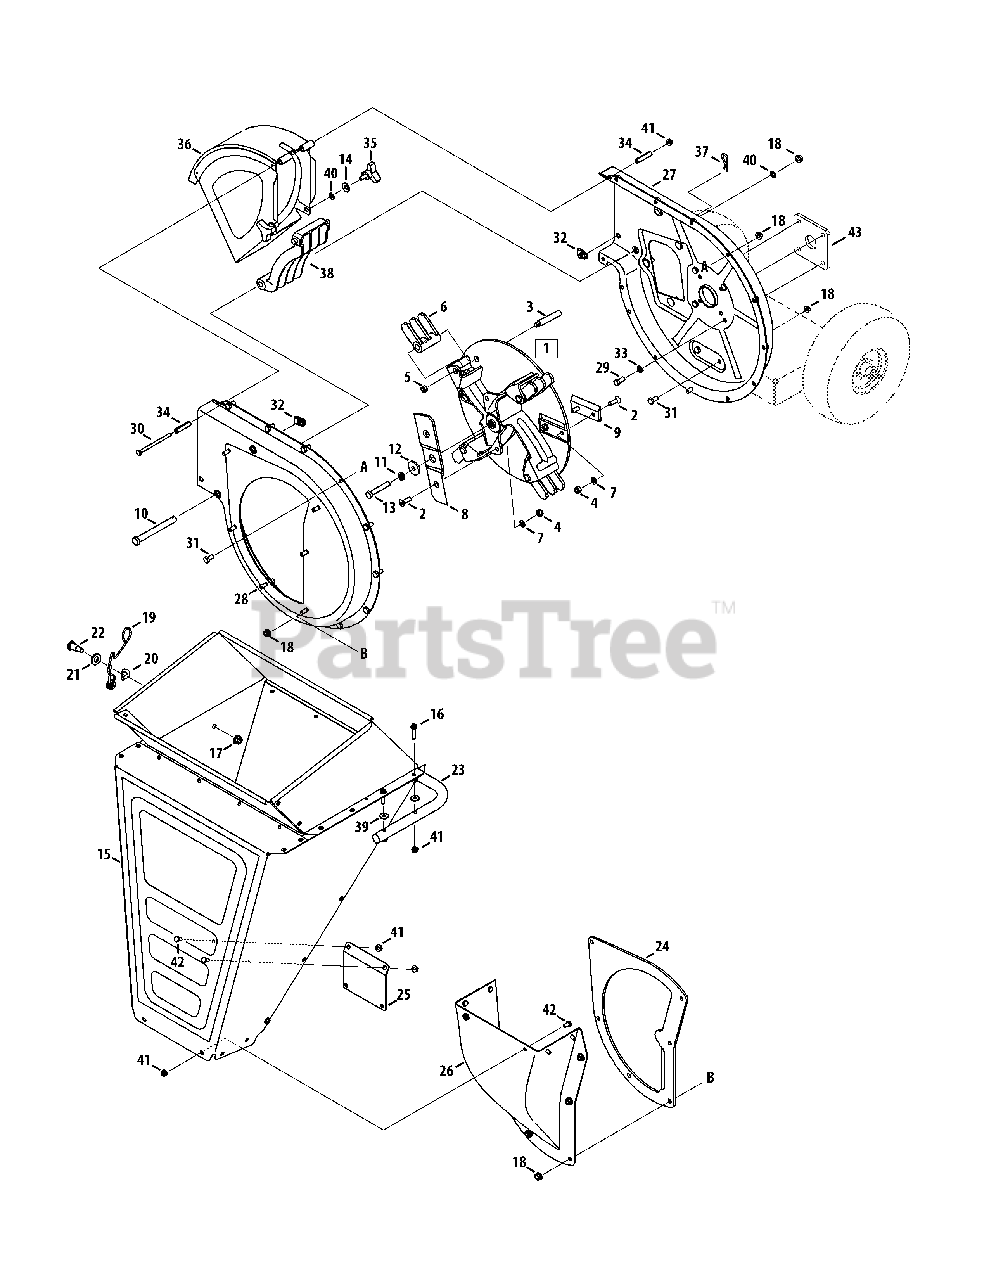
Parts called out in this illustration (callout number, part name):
1	Impeller Assembly Complete
2	Machine Screw, 5/16-24 x 1.0
3	Shoulder Pin, .5 x 2.625
4	Hex Lock Nut, 5/16-24
5	Nut, Jam Lock, 3/8-16
6	Flail Blade
7	Lock Washer, 5/16
8	Shredder Blade
9	Chipper Blade
10	Clevis Pin,.50 x 4.62
11	Lock Washer, 3/8
12	Flat Washer,.406 x 1.25
13	Hex Cap Screw, 3/8-24 x 2.2
14	Bell Washer.340 ID x.872 OD
15	Shredder Hopper Assembly
16	Hex Cap Screw, 1/4-20 x 1.250
17	Flange Lock Nut, 3/8-16
18	Flange Lock Nut, 5/16-18
19	Torsion Spring
20	Spring Washer,.50 x 1.0 x.022
21	Flat Washer,.50 x 1.0 x.0125
22	Shoulder Screw, 3/8-16,
23	Hopper Handle
24	Shredder Plate
25	Hopper Support Bracket
27	Inner Flail Housing Assembly
28	Outer Flail Housing Assembly
29	Hex Cap Screw, 5/16-24 x .75
29	Hex Cap Screw, 5/16-24 x 1.00
30	Hex Cap Screw, 1/4-20 x 3.75
31	Hex Cap Screw, 5/16-18 x .625
32	U-Nut, 5/16-18
33	Lock Washer, 5/16
34	Hinge Spacer,.265 x.380 x 1.66
35	Knob, 5/16-18
36	Chute Deflector Assembly
37	Internal Cotter Pin
38	Shredder Screen
39	Flat Washer, .28 x .74 x .063
40	Speed Nut,.3125ID
41	Nut, Flange, Lock, 1/4-20
42	TT Screw, 1/4-20 x .5
43	Engine Plate
